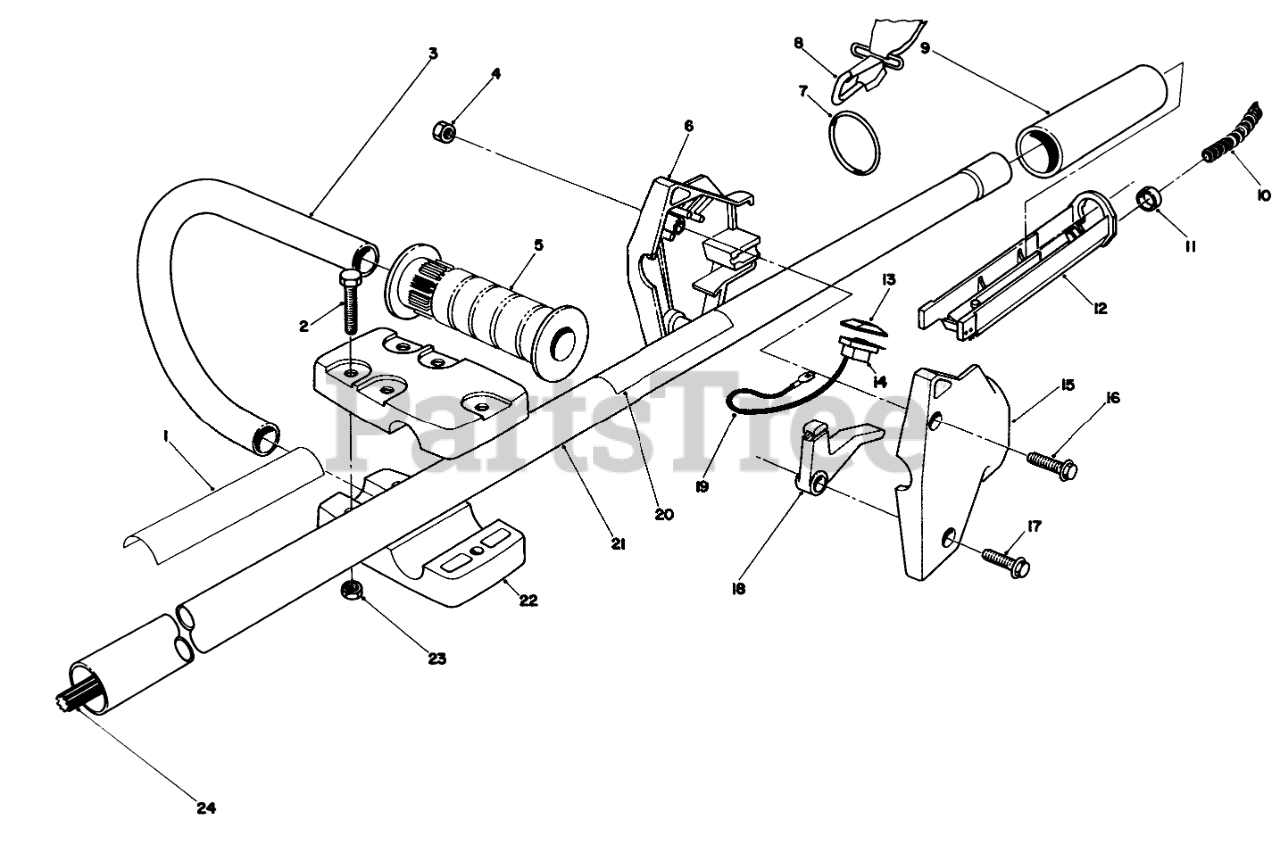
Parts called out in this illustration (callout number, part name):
1	Decal-TC 4000
2	SCREW-HH
3	Tube-Handle
4	NUT-LOCK, NI
5	LH GRIP
6	THROTTLE HSG.R H
7	RING-HARNESS
8	Harness
9	GRIP - RUBBER
10	Cover-Cable
11	RING FITTING
12	TROUGH 1"
13	SWITCH COVER-BLACK
14	SWITCH
15	THROTTLE HSG. L H
17	SCREW-HWH
18	THROTTLE LEVER
19	WIRE ASM
20	Decal
21	TUBE ASSEMBLY
22	CLAMP
23	NUT-LOCK, NI
24	SPLINED SHAFT
